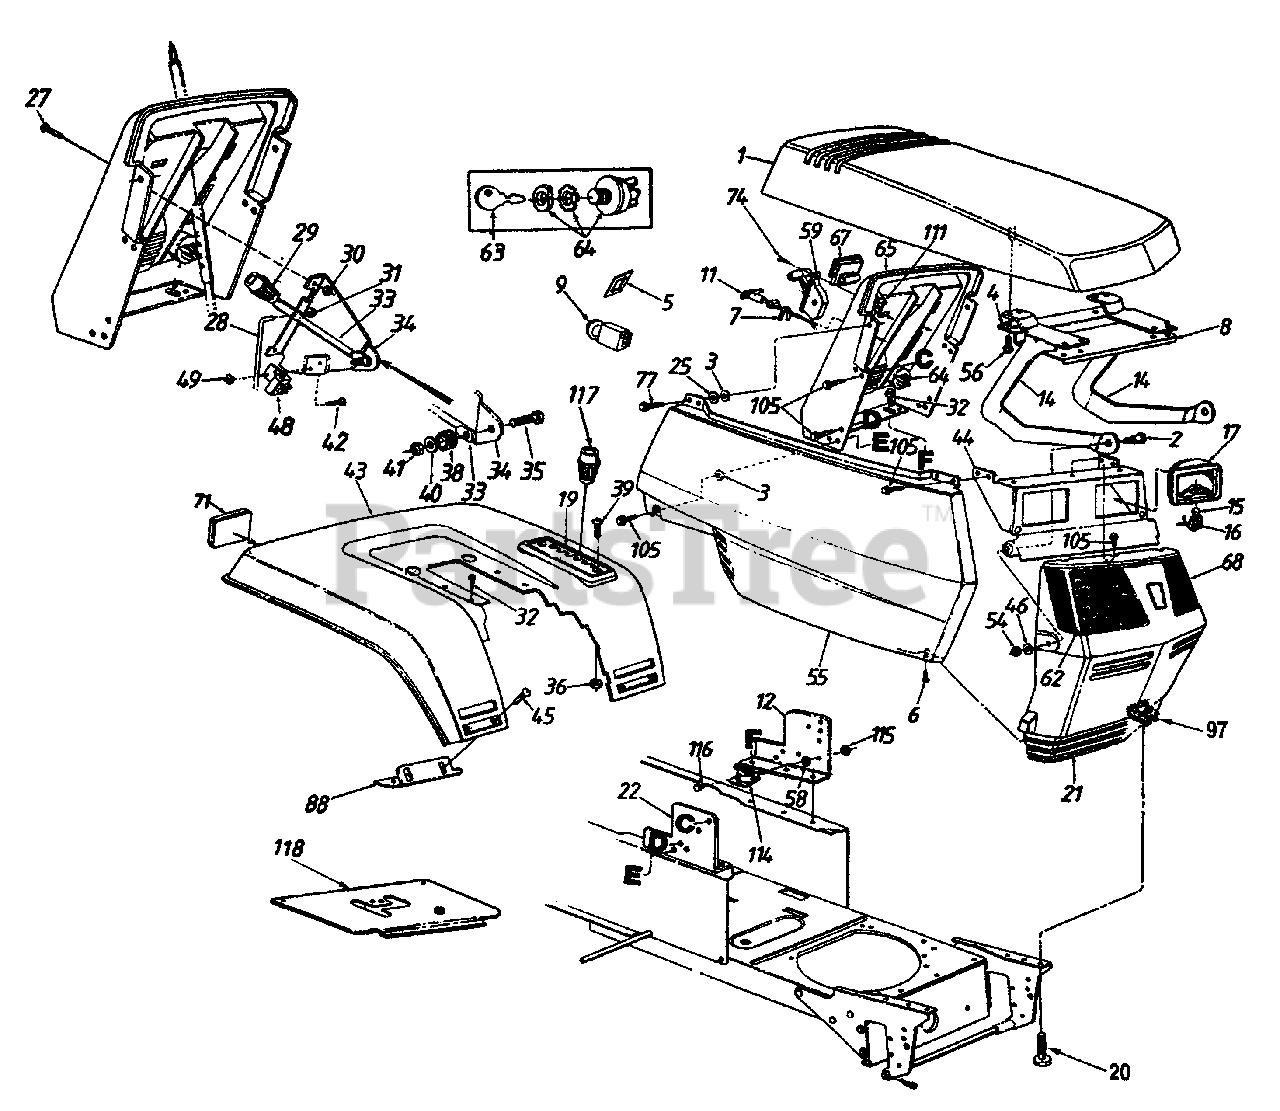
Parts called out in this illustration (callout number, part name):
1	Hood Ass'y.
2	Shld. Bolt .437" Dia. x .35"
3	Bolt Retainer 1/4" I.D.
6	Truss Mach. B-Tap Scr.#10 x .5" Lg.
7	Retainer Clip
11	Choke Control
16	Twist Lock-Lamp Socket
17	Headlight Housing
19	7-Speed Selector Plate
21	Grille
25	Fl-Wash. 1/4" I.D. x .93" O.D.
27	Truss Mach. Scr. 1/4-20 x .5" Lg.
28	Deck Control Rod
29	Knob-Blade Clutch
30	Hex Sems Nut 1/4-20 Thd.
31	Push Cap
32	Hex Wash. Hd. AB-Tap Scr. 5/16 x .75" Lg.
33	PTO Lever
36	Hex Sems Nut 1/4-20 Thd.
38	Rubber Washer
39	Truss Mach. Scr. 1/4-20 x .75" Lg.
40	Fl-Wash. .281" I.D. x .73"
41	Hex L-Nut 1/4-20 Thd.
42	Truss Mach. Scr. #10-24 x .5"Lg.
46	Fl-Wash. .328" I.D. x .68" O.D.
48	Safety Switch
49	Hex Nut #10-24 Thd.
54	Hex Cent. L-Nut 5/16-18 Thd.
55	Side Cover-R.H.
56	Hx Wash. Hd. B-Tap Scr. 1/4 x .5" Lg.
58	Ext. L-Wash. 1/4" I.D.
59	Throttle Control Box Ass'y.
62	Lens-R.H.
63	Ignition Key
64	Ignition Switch
65	Dash Panel
67	Ammeter
68	Lens-L.H.
71	Reflector
74	Truss Mach. AB-Tap Scr.#10 x .5" Lg.
77	Hex Wash. Hd. Tap Scr. 1/4 x .75" Lg.
105	Hex Tap Scr. 1/4-20 x .5" Lg.
111	Speed -Nut 1/4-20 Thd.
114	Solenoid
115	Hex Sems Nut 1/4-20 Thd.
116	Hex Bolt 1/4-20 x .5" Lg.
117	Shift Knob
